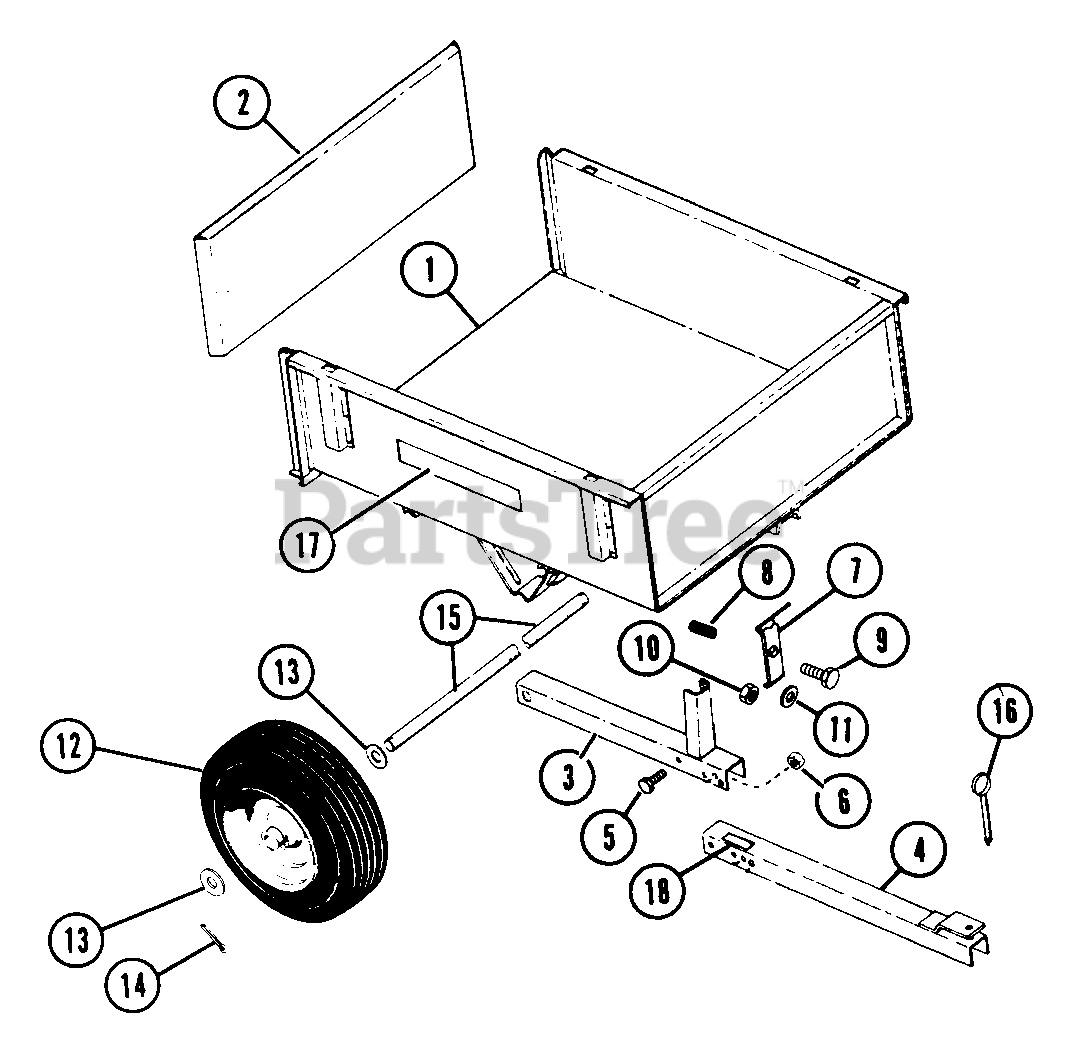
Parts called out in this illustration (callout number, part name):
2	TAILGATE
5	BLT-HEX .38-16X.75 PL GR5
6	NUT-LK .375-16 PL
7	LOCK LEVER
8	SG-COMP 1.44 FREE LENGTH
9	BLT-HEX .31-18X2.50 PL GR5
10	NUT-LK .312-18 PL
11	WSHR-FL-STL .38X.875X.083 PL
12	TIRES & WHEEL ASSY 4.30 X 8
12	BSHG (ND)
12	SUPPORT SEQMENT
13	WSHR-FL-STL 1.062X2.500X.165YZ
14	PIN-COTR .18X1.75 PL
16	LOCKING PIN
17	DECAL ARIENS
18	SERIAL NUMBER LABEL
